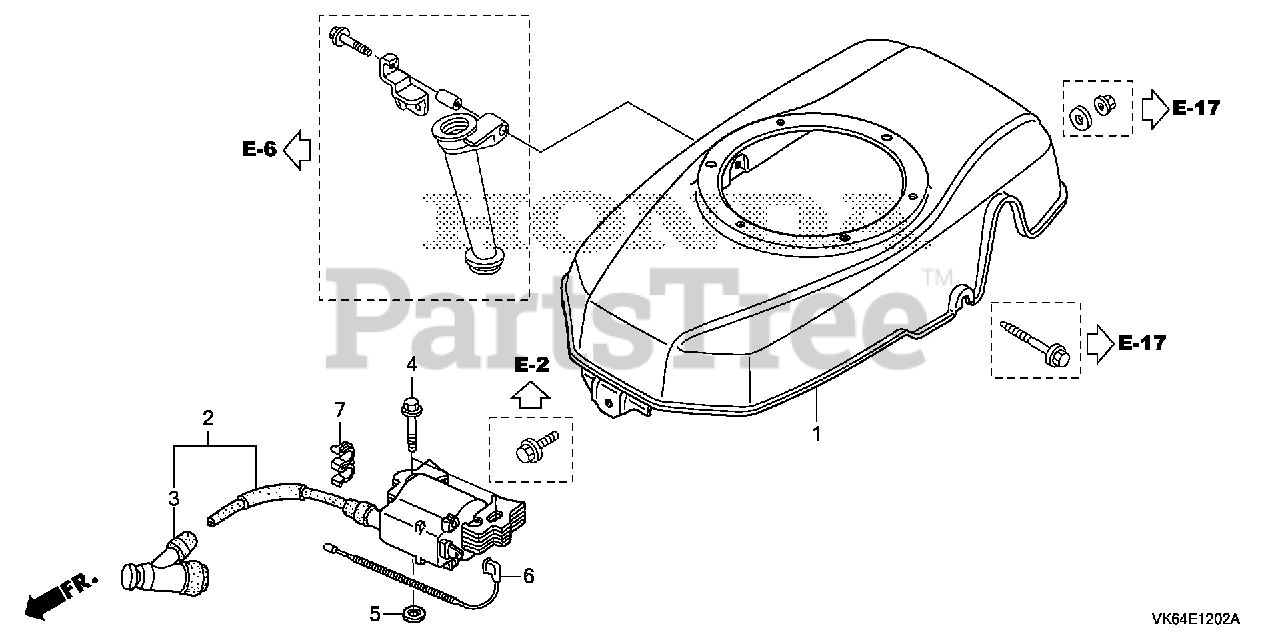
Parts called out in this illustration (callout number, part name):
1	COVER, FAN *R280* (POWER RED)
2	COIL ASSY., IGNITION
3	CAP ASSY., NOISE SUPPRESSOR
4	BOLT, FLANGE (6X28) (CT200)
5	WASHER, PLAIN (6MM)
